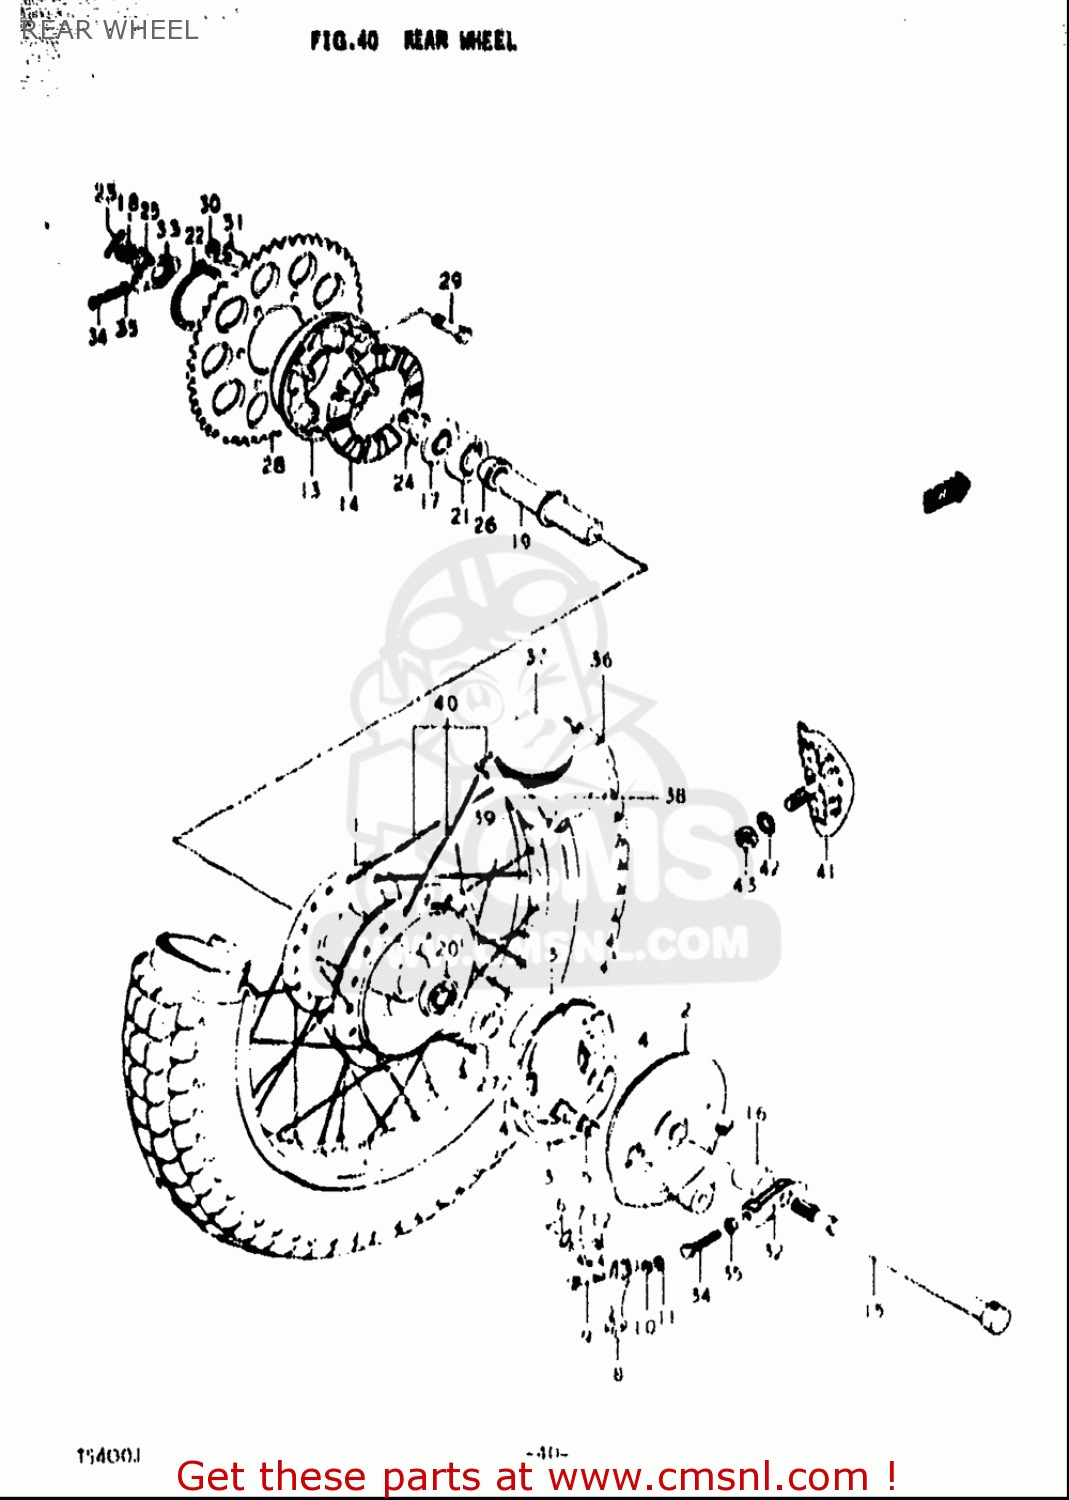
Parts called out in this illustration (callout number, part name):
6	O RING(D:2.4,ID:14.8)
7	WASHER(15.5X24X1.6)
9	BOLT
10	WASHER
11	NUT
12	SPRING
14	ABSORBER,RR WHEEL HUB SHOCK
15	AXLE,REAR
18	NUT
20	BEARING(15X42X13)
21	BEARING
22	CIRCLIP
23	PIN 30X40
24	SPACER,REAR AXLE,LEFT
25	NUT
26	SPACER,REAR HUB BEARING
28	SPROCKET,RR
29	BOLT(8X33.5)
31	WASHER
32	ADJUSTER,CHAIN,R
33	ADJUSTER,CHAIN,L
34	BOLT(8X50)
35	NUT
37	TUBE,INNER
38	PROTECTOR,INNER TUBE
39	RIM,WHEEL
40	SPOKE SET,RR
41	STOPPER,BEAD(1.85)
42	WASHER
